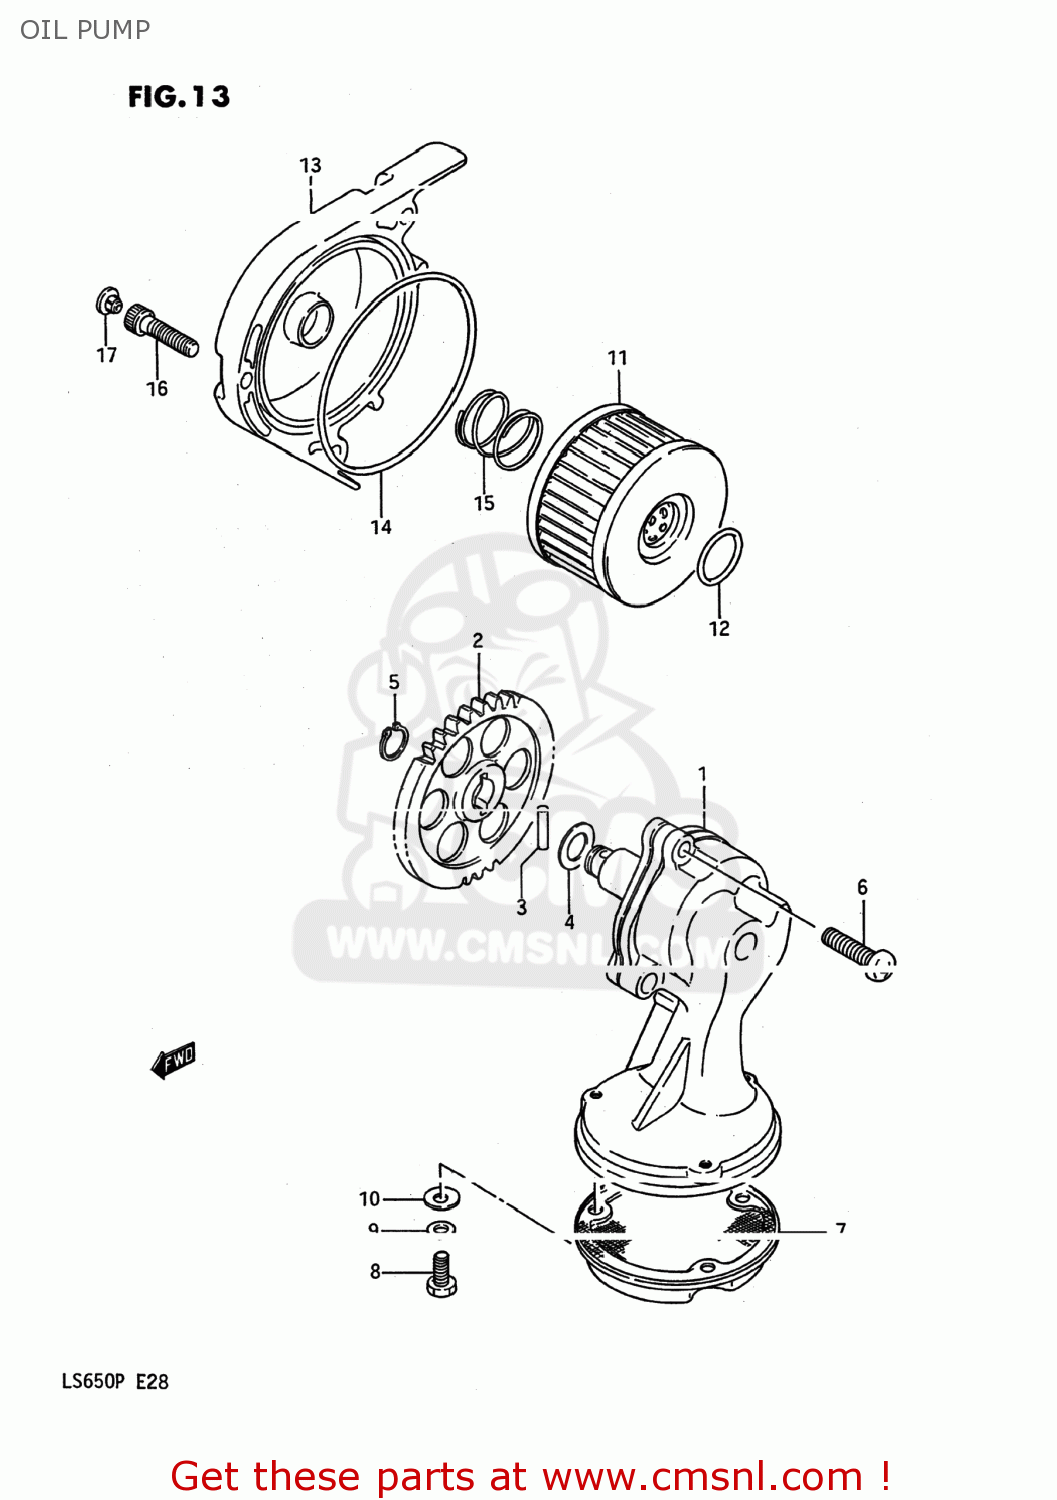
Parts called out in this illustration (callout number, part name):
1	PUMP ASSY,ENGINE OIL
2	GEAR,ENG OIL PUMP DRIVEN
3	PIN(4X15.8)
4	SHIM
5	CIRCLIP,10MM
6	SCREW
7	STRAINER,ENGINE OIL
8	BOLT 5X12
9	LOCK WASHER
10	WASHER
11	FILTER,ENGINE OIL
12	O RING(D:2.4,ID:15.8)
13	CAP,OIL FILTER
14	O RING(D:2.4,ID:73)
15	SPRING
16	BOLT
17	CAP(OD:10)
